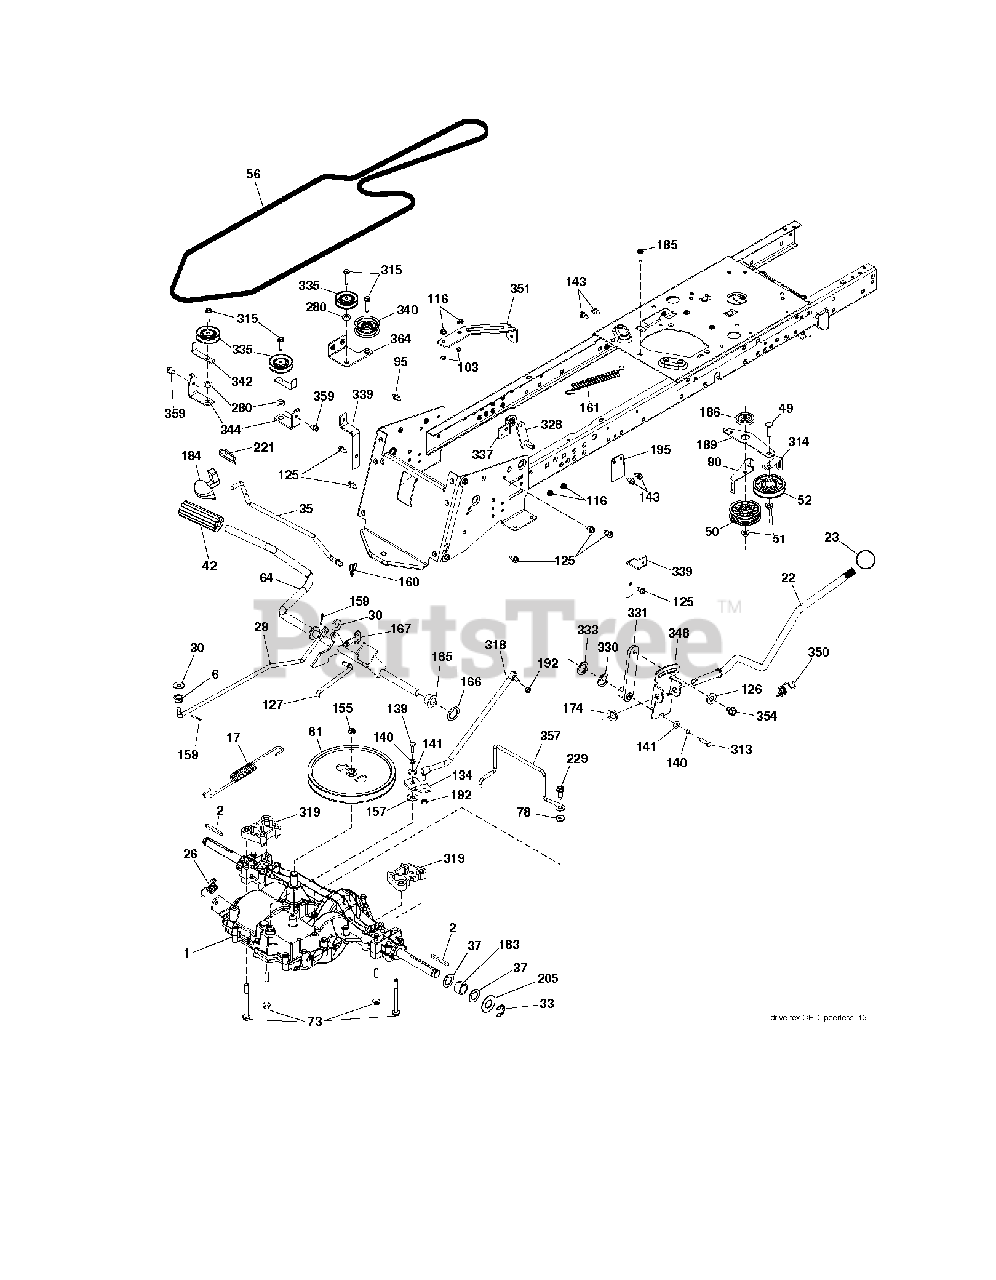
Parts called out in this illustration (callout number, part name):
2	SQUARE KEY
6	MANDREL ASS'Y
23	KNOB.DUCKHEAD.1/2
26	SPRING,BRAKE RETURN
33	E-RING LT
35	ROD, BRAKE, PARK
42	PEDAL COVER T
49	BOLT
51	NUT LOCK FLG 3/8-16 UNC
52	IDLER.V-GROOVE.910.OFFSET
64	SHAFT.ASM.PEDAL.BRAKE.
78	WASHER
95	SCREW, 3/8-16X3/4
103	JAM NUT TI
116	NUT LOCK HEX FLANGE 5/16-18
125	SCREW
126	WASHER.SRRTD.5/16
127	LINK.CLUTCH.GROUND.DRIVE
134	ARM SHIFT
139	BOLT 1/4-28X3/4
140	LOCKWASHER
141	WASHER LT
155	RETAINING RING LT
157	WASH-SHFT PLT LT
159	COTTER PIN
160	RETAINER CLIP
161	SPRING, RETURN LT
165	BUSHING.SHAFT.BRAKE.HAND
166	NUT.PUSH.625
167	LATCH.BRAKE.SPRING
174	NUT.PUSH.500.2006
183	SPACER AXLE
184	HANDLE.PARKING.BRK.PRED.LT.RED
186	SPACER.RETAINER
192	NUT LOCK CENTER 1/4 -28 FNTHD
221	RETAINER.SPRING.CLIP.H
229	SCREW 5/16-18X1
314	RETAIN BELT
315	BOLT.5/16-18X1.25
330	WASHER.NYL.7/8IDX.105"HYD CR
335	PULLEY.V-IDLER.
359	SCREW LT.3/8-46X5/8
